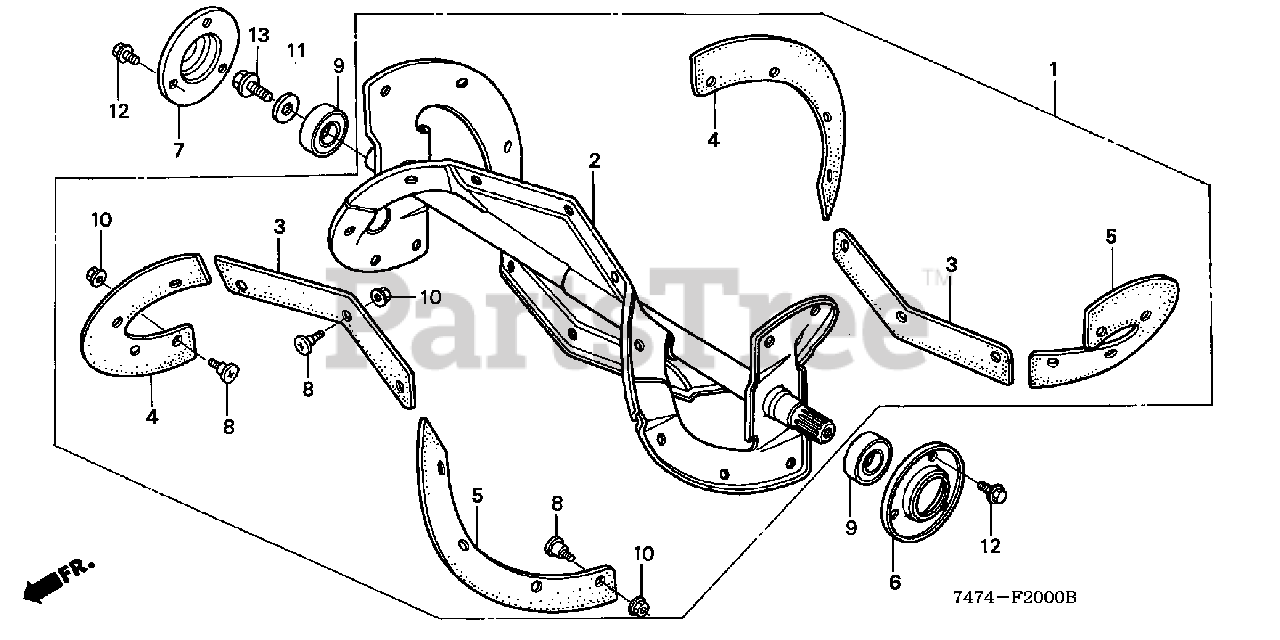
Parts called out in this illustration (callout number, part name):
1	AUGER ASSY.
3	RUBBER, BLOWER
4	RUBBER, R. AUGER
5	RUBBER, L. AUGER
6	HOLDER, L. AUGER
7	HOLDER, R. AUGER
8	BOLT, PAN (6X17)
9	BEARING, RADIAL BALL (6203)
10	NUT, SELF-LOCK (6MM)
11	WASHER (8MM)
12	BOLT, FLANGE (6X10)
13	BOLT, FLANGE (8X20)
